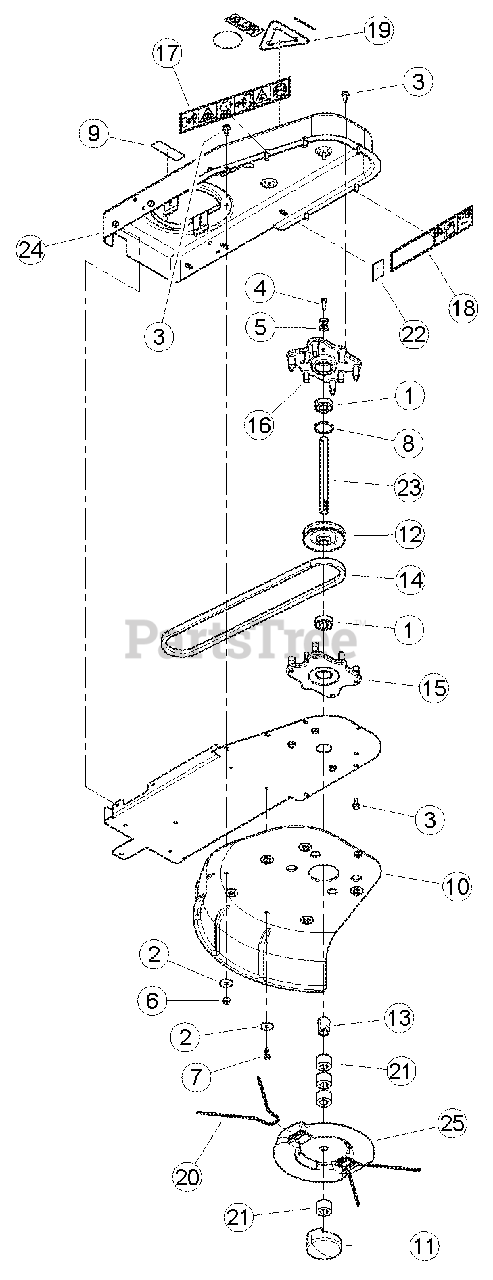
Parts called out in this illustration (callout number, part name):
1	BEARING, 3/4" BALL
2	WASHER, 5/16 FENDER
3	BOLT, 5/16 X 3/4 SERR FLANGE UNC
4	BOLT, 5/16 X 1 HEX GR8 PATCH ZP
5	WASHER, 5/16 GR8 USS ZP
6	NUT, 5/16-18 NYLOCK-FLANGE
7	SCREW, 5/16-18 X 1 INZP THREAD ROLLING
8	SNAPRING, 1.75 INTERNAL
9	DECAL, SERIAL NUMBER
10	SHIELD, TRIMMER
11	MOWBALL, CAST TRIMMER
12	PULLEY, 4.0 X 3/4 D-BORE B GROOVE
13	SPACER, SPINDLE WITH D-BORE
14	BELT, L550WRAPPED ARAMID
15	CASTING, BEARING HOUSING BOTTOM
16	CASTING, BEARING HOUSING TOP
17	DECAL, SAFETY INFORMATION
18	DECAL, MAINTENANCE INFORMATION
19	DECAL, WT24 AND RECLAIM
19	DECAL, WT24T AND RECLAIM
19	DECAL, WT24S AND RECLAIM
20	STRING, 20" X .175 DIA. CROSS-FIRE (SEE SERVICE PARTS & ACCESSORIES)
21	SPACER, 1.5" OD X .750" ID
22	DECAL, ECHO BEAR CAT QR CODE
23	SHAFT, TRIMMER SPINDLE
24	BODY, TRIMMER, WT24S
24	BODY, TRIMMER, WT24T
24	BODY, TRIMMER, WT24
25	DISK, TRIMMER HEAD
